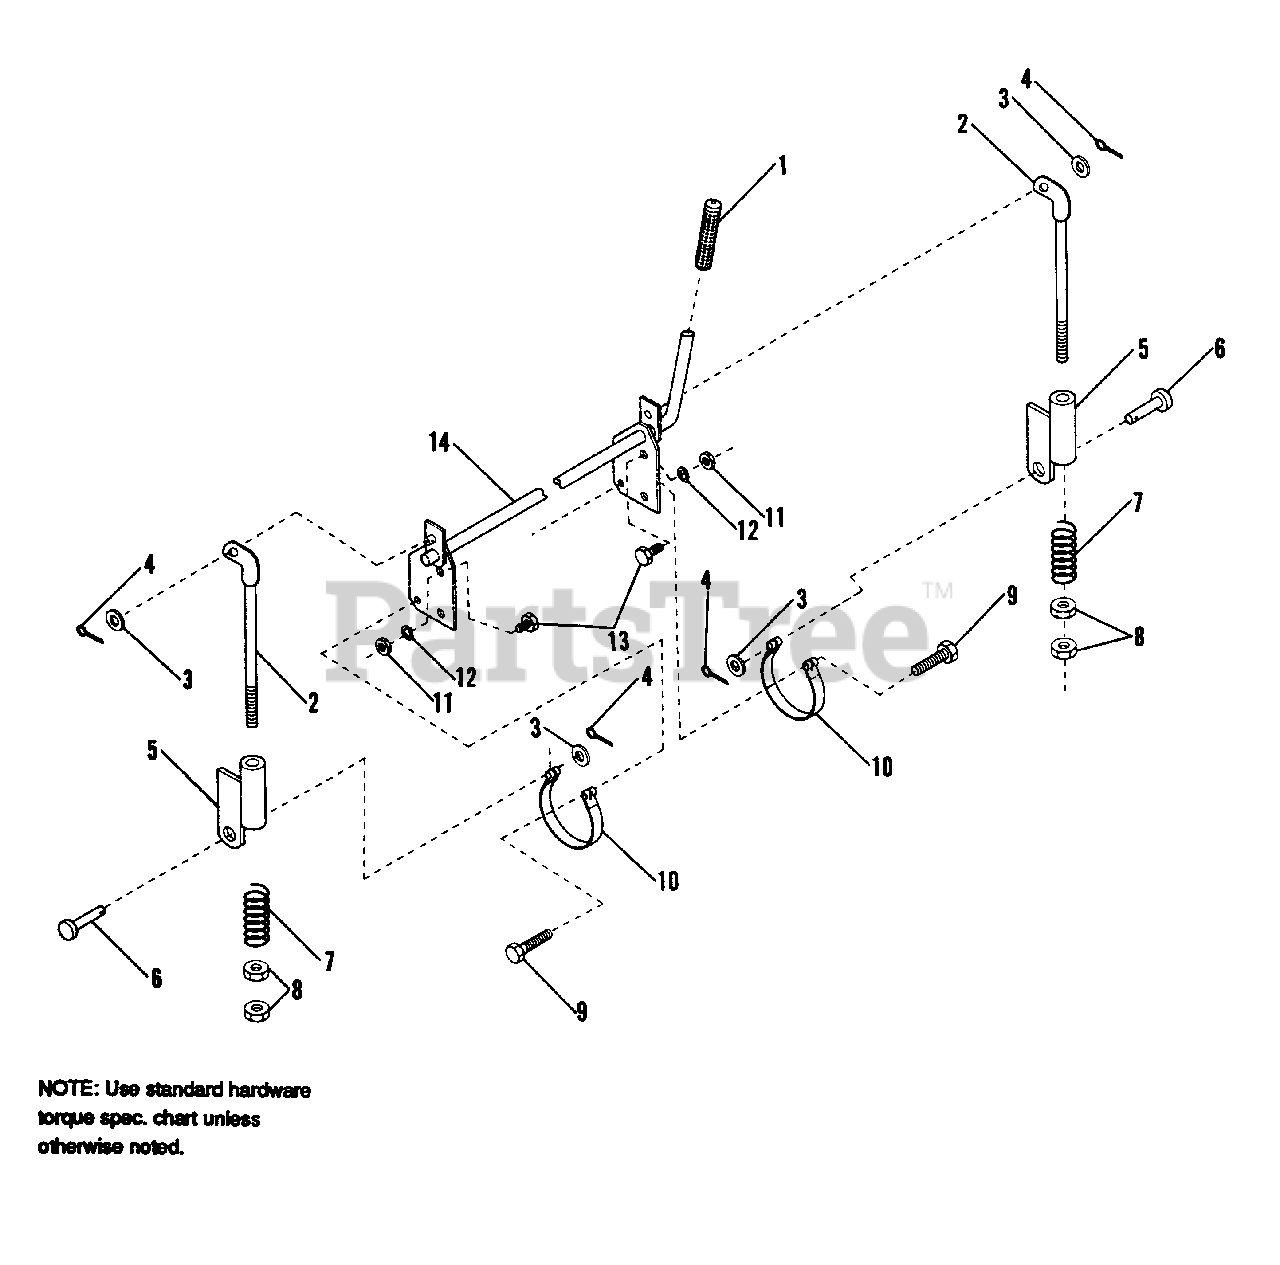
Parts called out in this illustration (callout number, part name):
2	ROD, Brake
3	WASHER, Plain
5	ROD GUIDE ASSY.
6	CLEVIS PIN
7	SPRING, Compression
8	NUT, Hex 5/16-18
9	CAPSCREW, Hex 5/16-18 x 1-1/2
10	BAND, Brake
11	NUT, Hex 3/8-16
12	LOCKWASHER, Spring 3/8
13	CAPSCREW, Hex 3/8-16 x 3/4
14	SHAFT ASSY.
